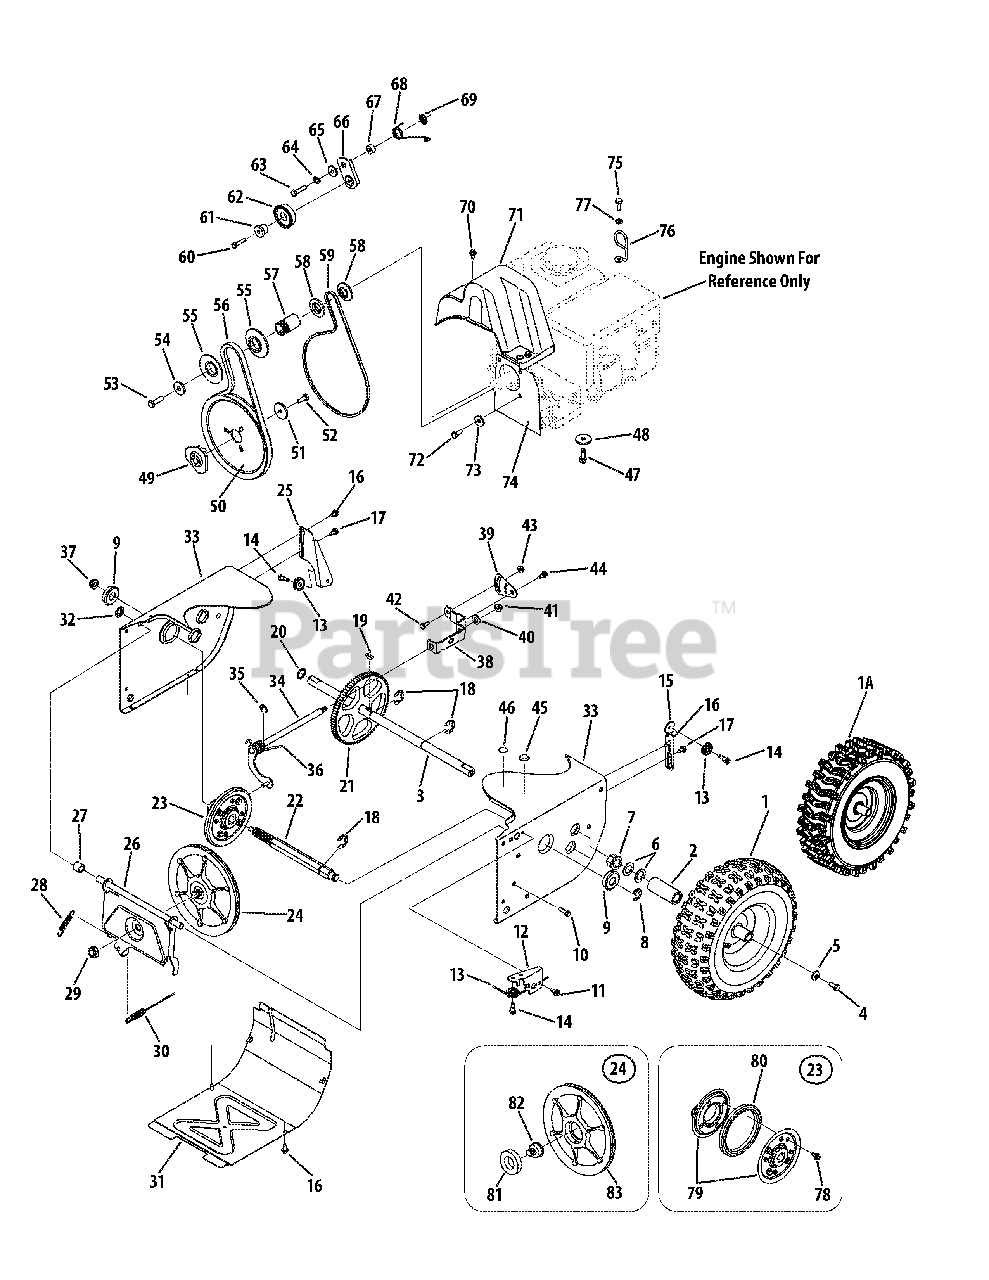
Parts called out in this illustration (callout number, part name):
2	Spacer, 1.25 OD x .75 ID x 3.00
3	Axle, .75 x 22
4	Hex Lock Screw, 5/16-24 x .750
5	Bell Washer, .340 x .872 x .060
6	Flat Washer, .793 x 1.24 x .06
7	Hex Flange Bearing, .75 ID
8	E-Ring, .750
9	Ball Bearing, 17 x 40 x 12
10	Hex Washer Screw, 1/4-20 x 1.000
11	Hex Washer Screw, 1/4-20 x .625
13	Cable Roller
14	Shoulder Screw, .340 x .335 x 1/4-28
16	Hex Washer Screw, 1/4-20 x .625
17	Shoulder Screw, .368 x .113 x 1/4-20
18	E-Ring, .875
19	Hi-Pro Key, 3/16 x 3/4
20	Flat Washer, .75 x 1.00 x .06
21	Gear, 80 Tooth
22	Hex Shaft, .8125 7 Tooth
23	Friction Wheel Assembly, 5.5 OD
24	Friction Disc Assembly
25	Drive Cable Guide Bracket
27	Spacer, .508 ID x .750 OD x .68
28	Extension Spring, .380 OD x 2.500
29	Flange Nut, 5/8 -18
30	Wheel Drive Cable
32	Speed Nut, .500
34	Rod Shift Assembly
35	E-Ring
36	Torsion Spring, .750 ID x .968
37	Flange Lock Nut, 3/8-16
40	Flat Washer, .469 x .875 x .105
41	Flange Lock Nut, 5/16-18
42	Hex Screw, 1/4-20 x .620
43	Flange Lock Nut, 1/4-20
44	Shoulder Screw, .368 x .113 x 1/4-20
45	Plug, 3/8 ID
46	Plug, 1/2 ID
47	Hex Washer Screw, 3/8-16 x 1.000
48	Flat Wsh., .38 x 1.38 x .125 (Tec/B&S)
49	Pulley Adapter
50	Auger Belt Pulley
51	Flat Washer, .34 x 1.50 x .150
52	Hex Screw, 5/16-24 x .875
53	Hex Screw, 3/8 -24 x 1.25
54	Flat Washer, .406 x 1.25 x .157
55	Pulley Half
56	Belt
57	Spacer, .875 ID x 1.185 OD
58	Pulley Half
59	V-Belt
60	Hex Washer Screw, 1/4-20 x 1.250
61	Shoulder Spacer, .260 x .785 x .538
62	Idler Puller Assembly
63	Hex Screw, 5/16-24 x 1.25
64	Lock Washer, 5/16
65	Shlder. Spcr., .3175 ID x .500 x .0975
66	Wheel Drive Idler Bracket
67	Spacer, .340 x .750 x .360
68	Torsion Spring, .850 ID x .333
69	Push-on Nut, .25
70	Hex Washer Screw, 1/4-20 x .625
71	Belt Cover
72	Hex Lock Screw, 5/16-24 x .750
73	Shoulder Spacer
75	Hex Screw, 1.25 x 20
76	Cable Control Wire
77	Flat Washer, .330 x .630 x .0635
78	Hex Washer Screw, 1/4-14 x .625
79	Friction Wheel Plate
80	Friction Wheel
81	Friction Disc Bearing Pin
82	Ball Bearing, 30 x 55 x 13
83	Friction Wheel Disc, .060 x 8.0
